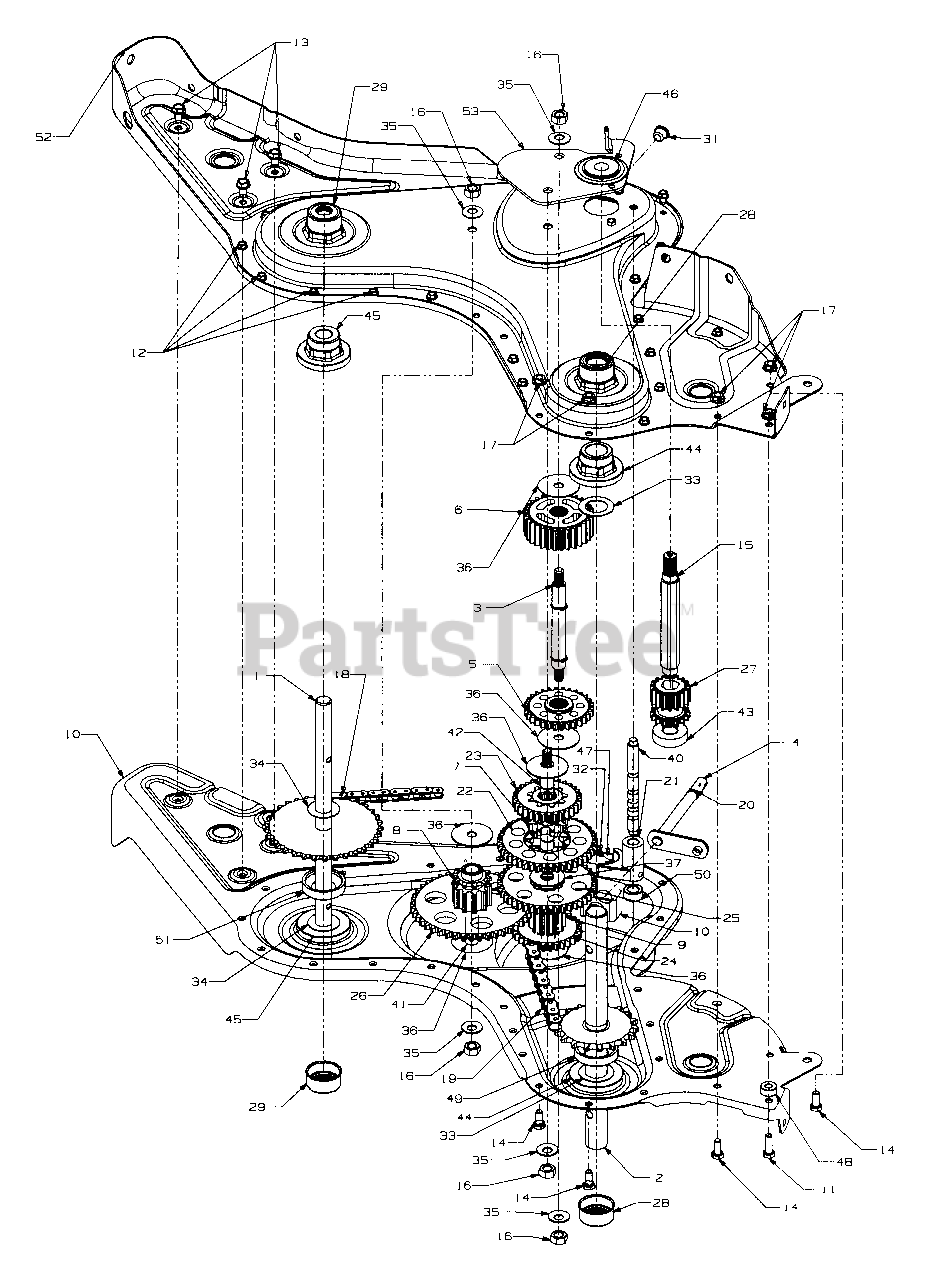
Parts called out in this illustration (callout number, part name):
1	Wheel Shaft Ass'y: 33T
2	Tine Shaft Ass'y: 1ST
3	Jack Shaft Ass'y
4	Input Shaft Ass'y
5	Rev. Idler Gear Ass'y: 307
6	Ftine Idler Gear Ass'y: 30T
7	Tine Input Sprocket Ass'y: 9T
8	Wheel Input Sprocket Ass'y: 10T
9	Gear Ass'y: 11T
11	Hex Bolt 5/16-18 x 1" Lg.
12	Hex S-Tap Scr .1/4-20 x .5"
13	Hex S-Tap Scr .5/16-18 x .625"
14	Hex Bolt 5/16-18 x .75"
15	Input Shaft
16	Hex Nut 7/16-20
17	Flange Nut 5/16-18
18	#420 Chain 1/2 Pitch x 50 Links
19	#50 Chain 5/8 Pitch x 54 Links
20	Snap Ring
21	Shifting Fork
22	Spur Gear 44T
23	Spur Gear 30T
24	Spur Gear 30T
25	Spur Gear 44T
26	Spur Gear 44T
27	Spur Gear 16T
28	Seal 1.0 Shaft
29	Seal .75 Shaft
31	Taper Cap Ring
32	Compression Spring .50" Lg.
33	Thrust Wash. 1.03" I.D. x 1.62"
34	Fl-Wash .76" I.D. x 1.5" O.D.
35	Bell-Wash .45" I.D. x 1.0"
36	Thrust Wash. .445 x 1.92 x .060
37	Fl-Wash. .635" I.D. x 1.59 O.D.
40	Detent Shaft 1/2" Dia.
41	Jack Shaft .625 x 2.385
42	Jack Shaft .625 x 5.0
43	Ball Bearing
44	Flange Bearing 1.0 x 2.5 x 1.38
45	Flange Bearing .75 x 2.5 x 1.38
46	Ball Bearing .6692 x 5745 x .466
47	Detent Ball .250
48	Spacer .315
49	Spacer 1.0 I.D x 2.0 O.D. x .440
50	Spacer .505 I.D. x .88 O.D. x .440
51	Spacer .75 x 2.0 x .50
53	Gear Positioner Bracket
